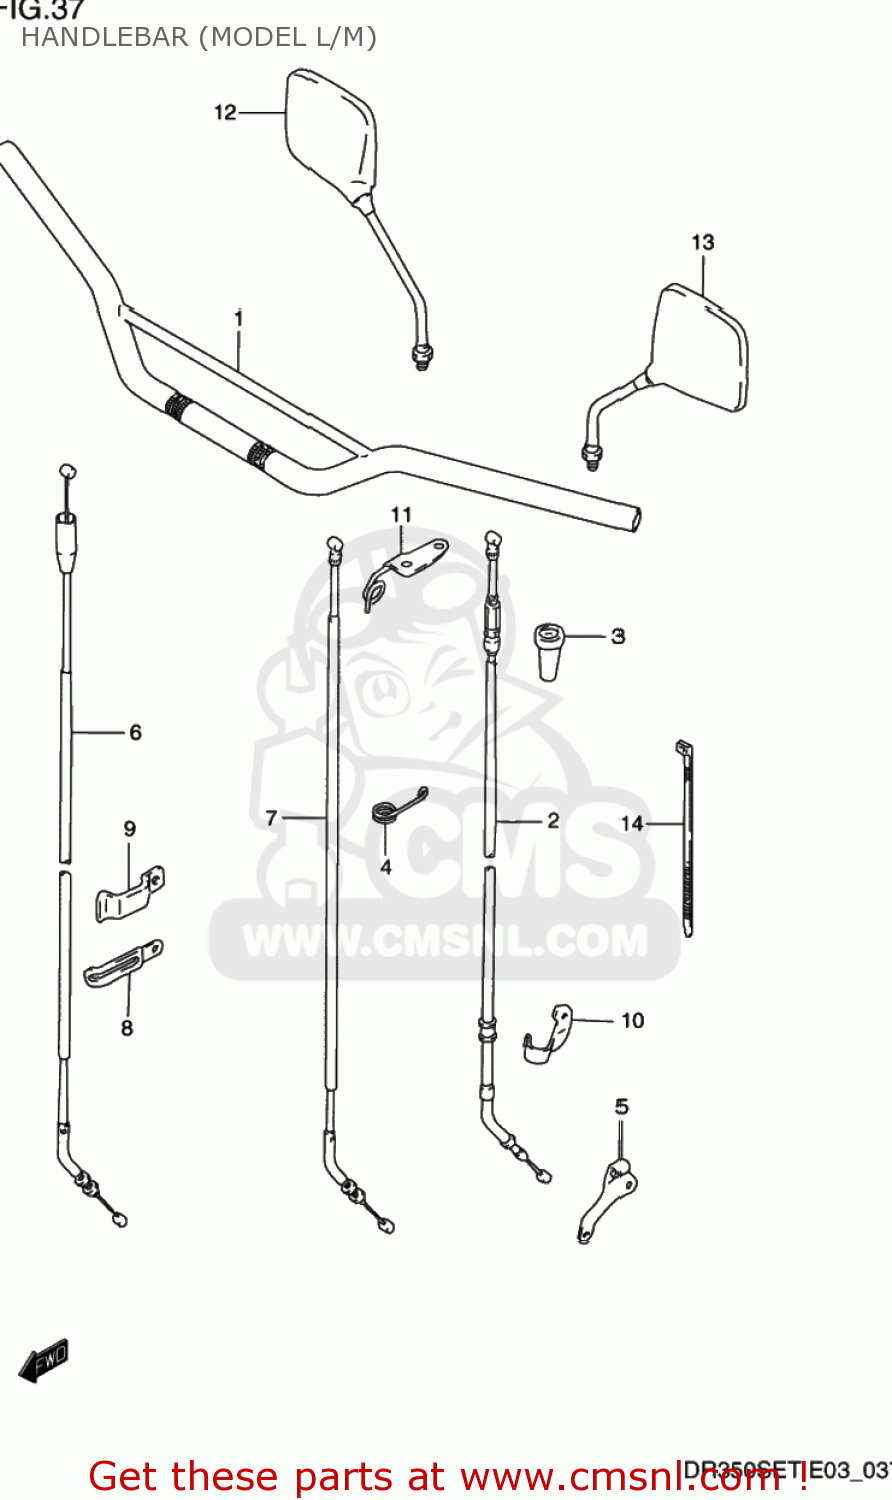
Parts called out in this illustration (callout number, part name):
1	HANDLEBAR
2	CABLE ASSEMBLY,CLUTCH
3	BOOT,CLUTCH CABLE
4	GUIDE,CLUTCH CABLE
5	STOPPER,CLUTCH CABLE
6	CABLE ASSY,THROTTLE
7	CABLE ASSY DECOMP
8	CLAMP
9	CLAMP
10	CLAMP,CLUTCH CABLE
11	GUIDE,CABLE
12	MIRROR ASSEMBLY,REAR VIEW
13	MIRROR ASSEMBLY,LEFT
14	CLAMP(L:100)
